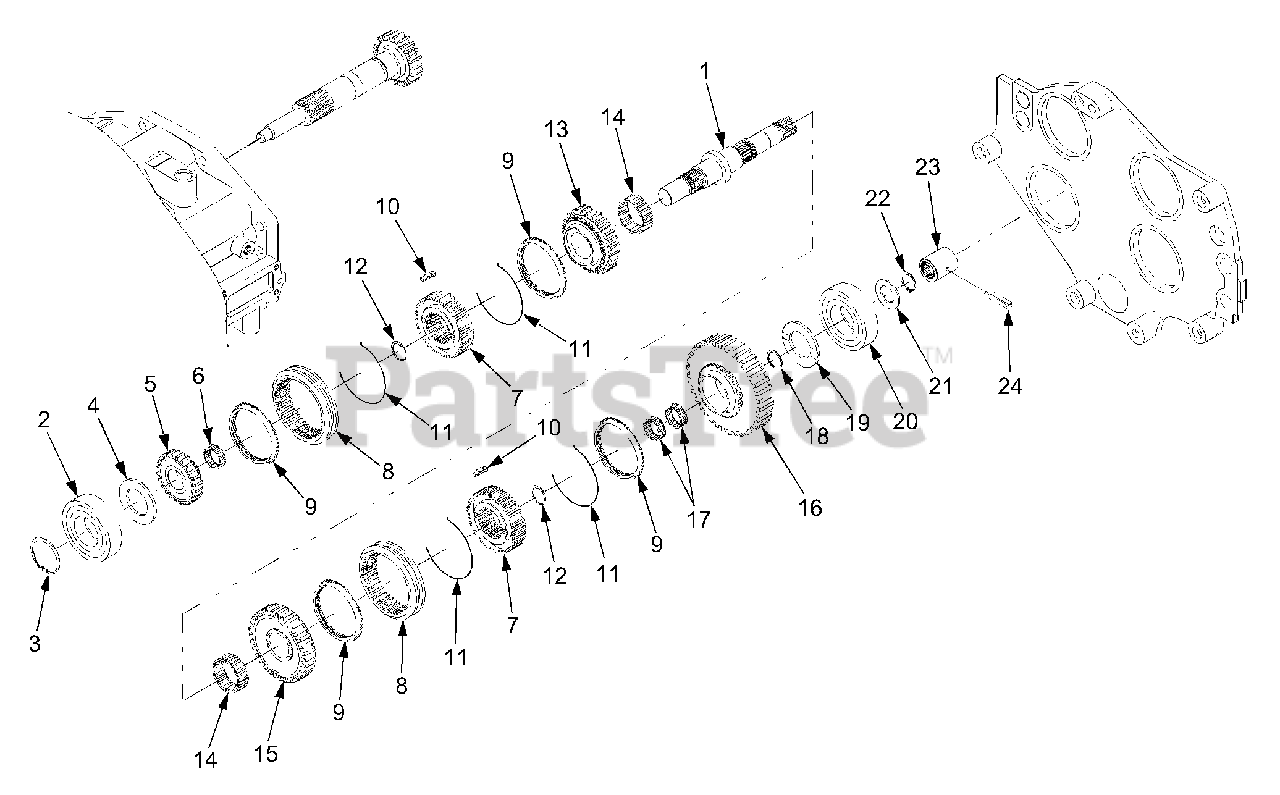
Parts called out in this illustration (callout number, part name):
1	Shaft, Counter
2	Bearing, Ball
4	Collar, Thrust
6	Bearing, Needle
8	Shifter
9	Ring, Synchronize
10	Key, Synchronize
14	Bearing, Needle
17	Bearing, Needle
19	Collar, Thrust
20	Bearing, Ball
